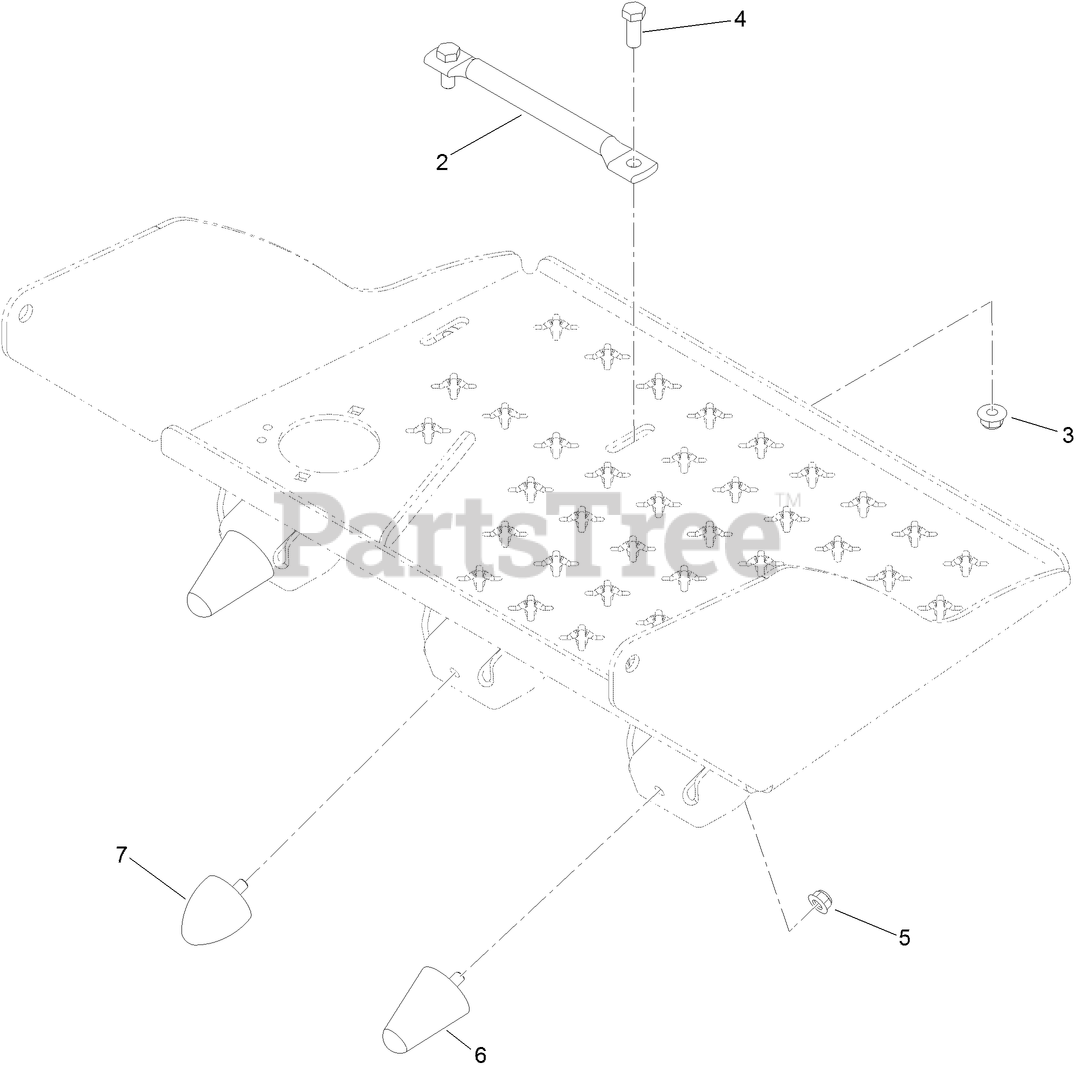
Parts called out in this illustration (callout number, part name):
2	ROCKER-PEDAL, FOOT
3	NUT-HF, NI
4	SCREW-HH
5	NUT-HF, NI
6	BUMPER-RUBBER
7	BUMPER-RUBBER
